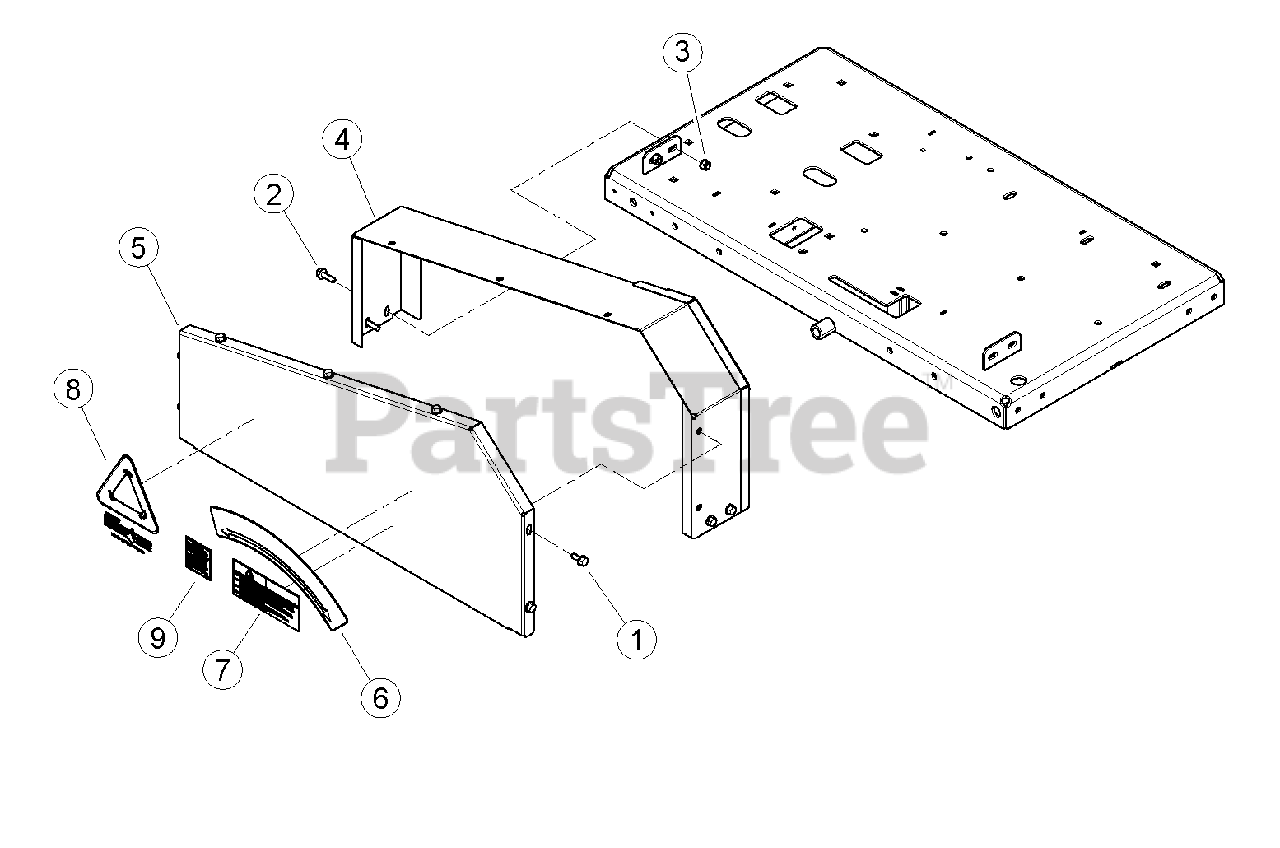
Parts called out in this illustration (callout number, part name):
1	BOLT, 5/16 X 3/4 FLANGE NC
2	BOLT, 5/16 X 1 FLANGE NC
3	NUT, 5/16-18 NYLOCK FLANGE
4	WELDMENT, SHIELD
5	SHIELD, CH4400 BELT SERVICE
6	DECAL, START/ENGAGE
7	DECAL, MUTILINGUAL MANUAL
8	LOGO, CHIP IT (WHITE)
9	DECAL, SPARK ARRESTOR
